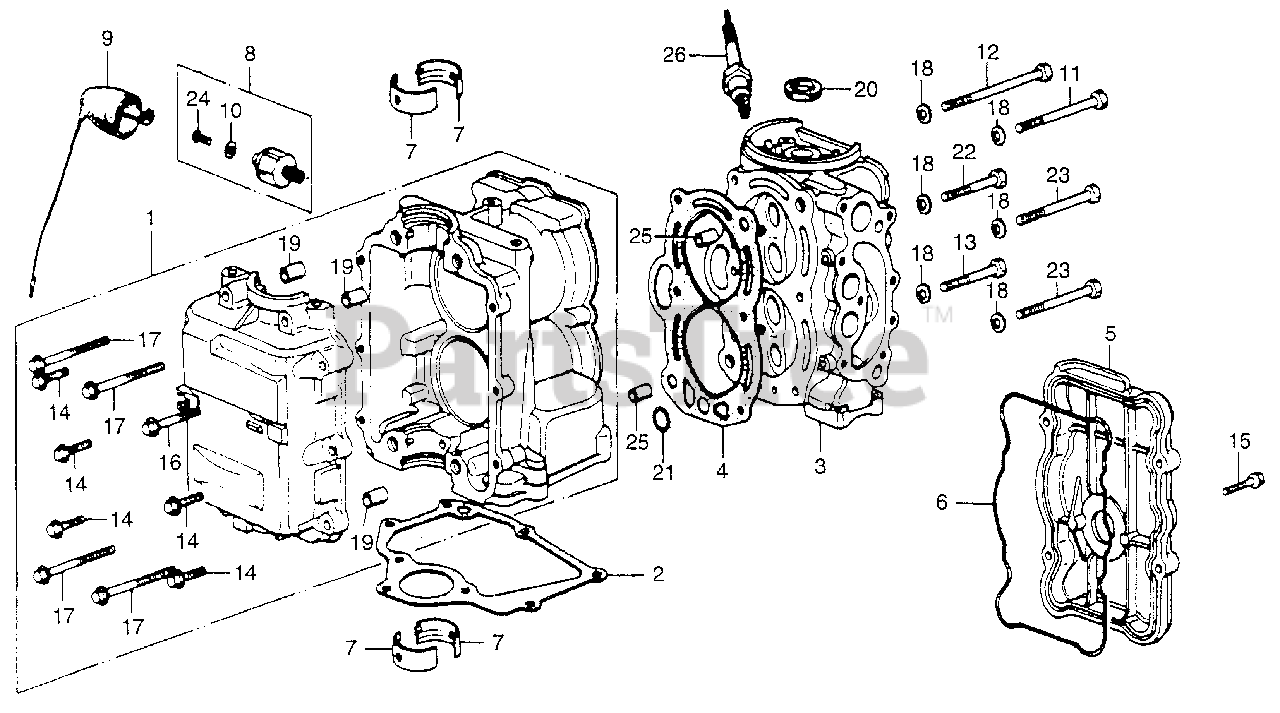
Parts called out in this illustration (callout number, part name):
1	CYLINDER ASSY.
2	GASKET, OIL PAN
3	CYLINDER HEAD (NOT AVAILABLE)
4	GASKET, CYLINDER HEAD
5	COVER, CYLINDER HEAD *NH8* (DARK GRAY)
6	GASKET, CYLINDER COVER
7	BEARING, CRANKSHAFT
8	SWITCH, OIL PRESSURE
9	WIRE, OIL PRESSURE SWITCH
10	WASHER (4MM)
11	BOLT, HEAD (8X70)
12	BOLT, HEAD (8X94)
13	BOLT, HEX. (8X55)
14	BOLT, FLANGE (6X25)
15	BOLT, FLANGE (6X28)
16	BOLT, FLANGE (6X35)
17	BOLT, FLANGE (8X45)
18	WASHER, HEAD (8MM)
19	PIN, DOWEL (10X12)
20	OIL SEAL (16X28X6)
21	O-RING (10.8X2.4) (ARAI)
22	BOLT, HEX. (8X50) (NOT AVAILABLE)
23	BOLT, HEX. (8X65) (NOT AVAILABLE)
24	SCREW, PAN (4X6)
25	PIN A, DOWEL (10X16)
26	SPARK PLUG (DR4HS) (NGK)
26	SPARK PLUG (DR5HS) (NGK)
